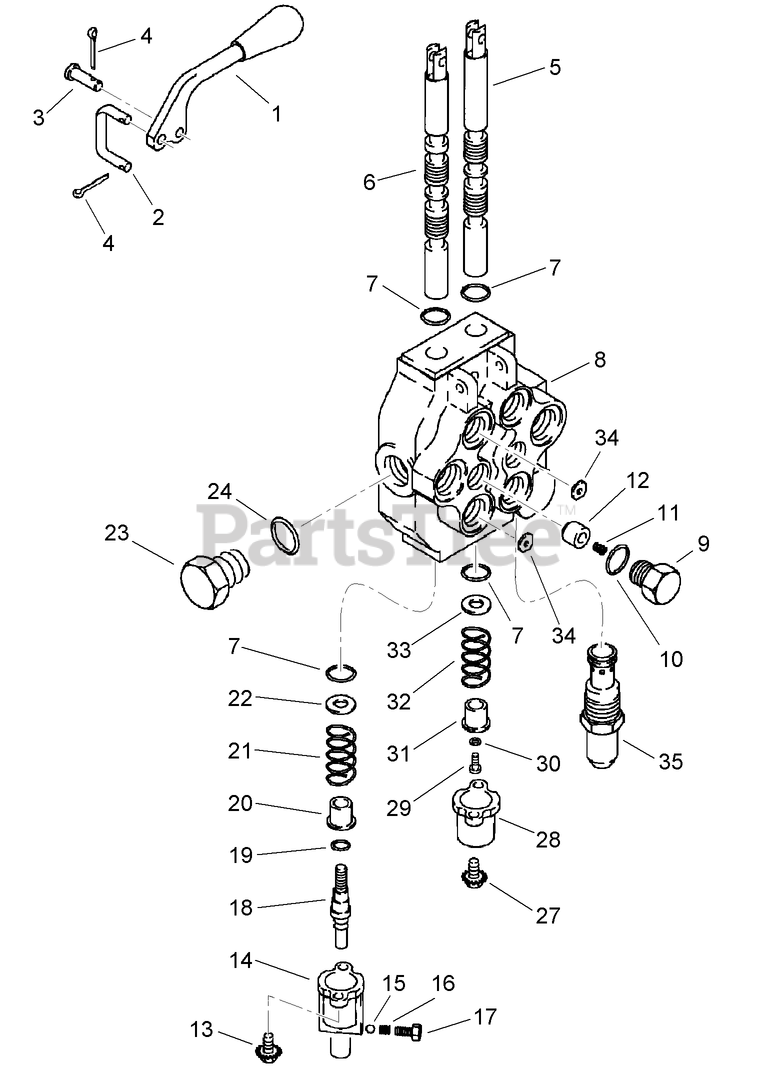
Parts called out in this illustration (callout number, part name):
1	HANDLE - Control, Plow Lift and Swing
3	PIN-CLEVIS
4	PIN-Cotter 0.062 x 0.75 in ZN
5	SPOOL - Plow Control Valve, Lift Section
6	SPOOL - Plow Control Valve, Swing Section
8	BODY - Control Valve
9	PLUG - Load Check
10	O-RING - Plug
11	SPRING - Load Check
12	POPPET - Load Check
13	SCREW - Includes Lock Washer, Detent Float
14	HOUSING - Detent
15	BALL - Detent Cap
16	SPRING - Detent
17	PLUG - Detent
18	SPOOL - Detent
19	O-RING - Detent Spool
20	SEAT - Spring, Lift Spool
21	SPRING - Return
22	WASHER - Lift Spool
23	PLUG - Hex, Power Beyond Port
24	O-RING - 59/64 ID x 7/64 inch Wide
27	SCREW - Includes Lock Washer
28	CAP - Bucket Spool End
29	BOLT - Hex Socket, No. 10 NF x 1/2 inch
30	WASHER-FLAT
31	SEAT - Spring, Spool
32	SPRING-RETURN
33	WASHER - Spring Seat, Spool
34	PLATE - Orifice
35	VALVE - Relief
